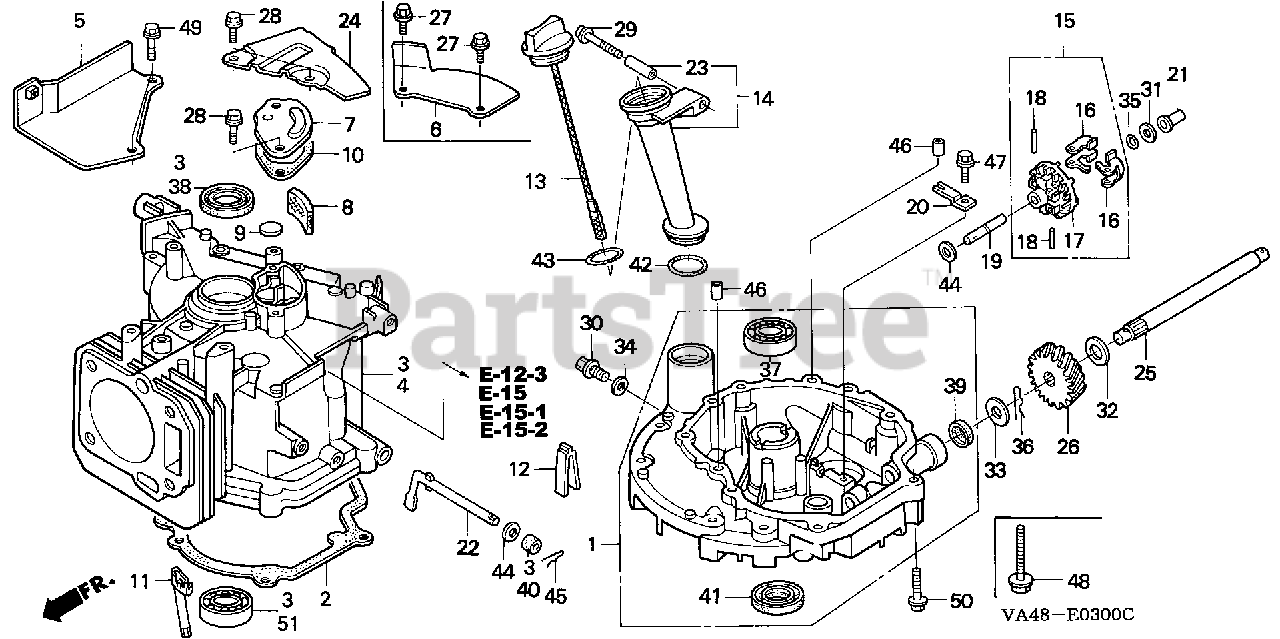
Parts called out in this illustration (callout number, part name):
1	PAN KIT, OIL
2	GASKET, OIL PAN (HPE)
4	CYLINDER
5	PLATE, GUIDE
7	CAP, BREATHER CHAMBER
8	FILTER, BREATHER
9	VALVE, BREATHER
10	GASKET, BREATHER CHAMBER
11	PIPE, OIL DEFENSE
13	GAUGE, OIL LEVEL Use up to Engine SN 1257294.
14	EXTENSION, OIL FILLER (106MM)
15	GOVERNOR ASSY.
16	WEIGHT, GOVERNOR
17	HOLDER, GOVERNOR WEIGHT
18	PIN, GOVERNOR WEIGHT
19	SHAFT, GOVERNOR HOLDER
20	PLATE, GOVERNOR SHAFT HOLDER
21	SLIDER, GOVERNOR
22	SHAFT, GOVERNOR ARM
23	COLLAR, EXTENSION Use up to Engine SN 1257294.
24	STAY, TANK
25	SHAFT, DRIVE
26	GEAR, DRIVEN (22T)
28	BOLT, FLANGE (6X14)
29	BOLT, FLANGE (6X32)
30	BOLT, DRAIN PLUG
31	WASHER, THRUST (6MM)
32	WASHER, THRUST (12MM)
33	WASHER (10X21)
34	WASHER, DRAIN PLUG (10.2MM)
35	CLIP, GOVERNOR HOLDER
36	PIN, LOCK (2.0)
38	OIL SEAL (22X35X6)
39	OIL SEAL (12X20X5) (ARAI)
40	OIL SEAL (6X11X4)
41	OIL SEAL (25X38X7) (ARAI)
42	O-RING (22.5X2.2) Use from Engine SN 1257295.
43	O-RING (26X2.7)
44	WASHER, PLAIN (6MM)
45	PIN, LOCK (8MM)
46	PIN A, DOWEL (8X14)
47	BOLT, FLANGE (6X12) Use from Engine SN 2086984.
49	BOLT, FLANGE (6X20)
50	BOLT, FLANGE (6X28)
NI	GOVERNOR KIT
